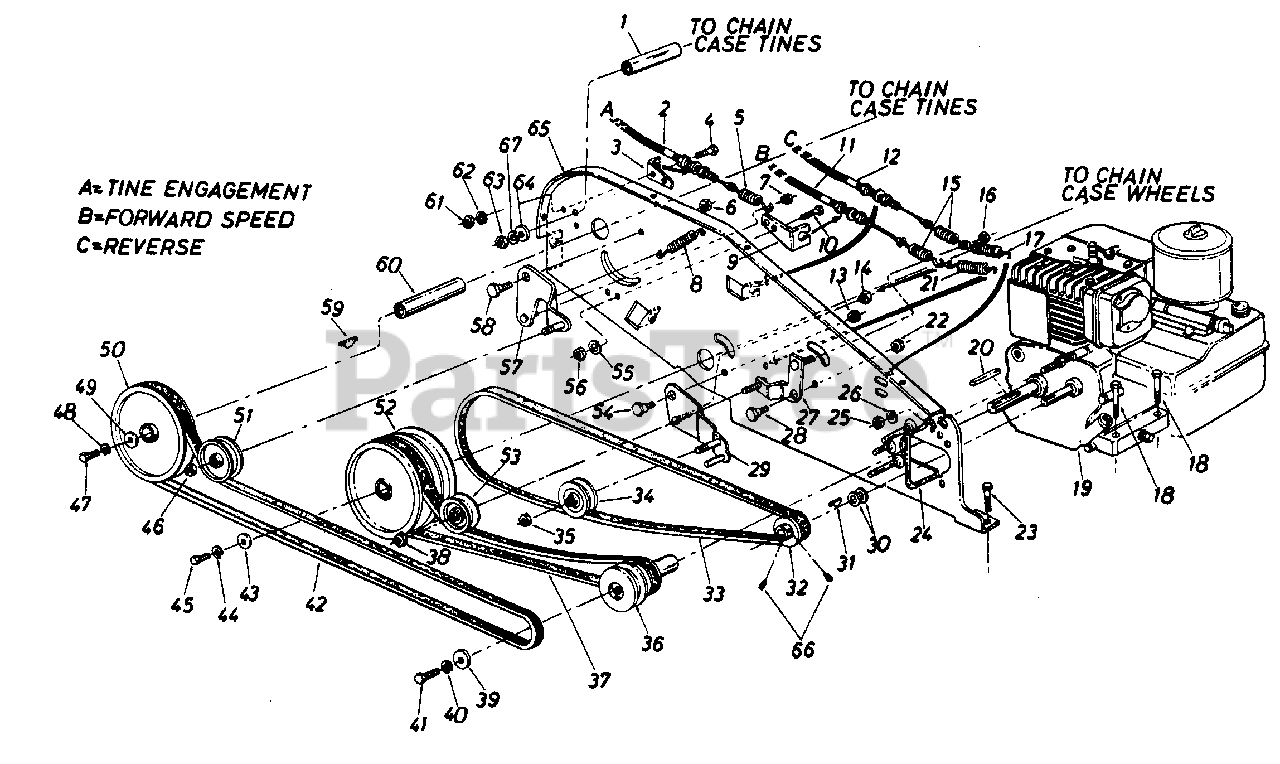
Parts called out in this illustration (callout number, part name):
1	Spacer.375" I.D. x .500" O.D. x 2.00" Lg.
2	Clutch Control Cable
3	Clutch Cable Bracket
4	Hex Bolt 5/16-18 x .75" Lg.*
5	Extension Spring .50" O.D. x 2.50" Lg.
6	Hex Cent. L-Nut 3/8-16 Thd.
7	Hex Cent. L-Nut 1/4" Thd.
8	Extension Spring .50" O.D. x 1.55" Lg.
9	Clutch Cable Bracket
10	Hex Bolt 5/16-18 x .75" Lg.*
11	Clutch Control Cable 42" Lg.
12	Clutch Control Cable 41" Lg.
13	Hex Cent. Nut 3/8-16 Thd.
14	Hex Cent. L-Nut 1/4-20 Thd.
15	Springs
16	Hex Cent. L-Nut 1/4-20 Thd.
17	Extension Spring .41" O.D. x 2.05" Lg.
18	Hex Bolt 5/16-18 x 1.50" Lg.*
20	Sq. Key 3/16 x 1.00" Lg.
21	Extension Spring .50" O.D. x 2.75" Lg.
22	Hex Cent. L-Nut 3/8-16 Thd.
23	Hex Bolt 5/16-18 x .75" Lg.*
24	Belt Keeper
25	Hex Nut 1/4-20 Thd.*
26	Bell-Wash. .265" I.D. x .75" O.D.
31	#5 Hi-Pro-Key 1/8" x 5/8" Dia.
32	1/2" V-Pulley 2.25" O.D. x .503" I.D.
33	"V"-Belt 1/2" X 43.0" Lg.
34	"V"-Belt Idler 2.62" O.D.
35	Hex Ins. L-Nut 3/8-24 Thd.
36	1/2" "V" Pulley Ass'y.
37	"V"-Belt 1/2" X 39.0" Lg.
38	Hex Ins. L-Nut 3/8-24 Thd.
39	Fl-Wash. .344" I.D. x 1.125" O.D.
40	L-Wash. 5/16" I.D.*
41	Hex Bolt 5/16-24 x 1.00" Lg.*
42	"V"-Belt 1/2" X 54.0" Lg.
43	Fl-Wash. 1/4" I.D. x .93" O.D.
44	L-Wash. 1/4" I.D.*
45	Hex Bolt 1/4-28 X .75" Lg.
46	Hex Ins. L-Nut 3/8-24 Thd.
47	Hex Bolt 1/4-28 X .75" Lg.
48	L-Wash. 1/4" I.D.*
49	Fl-Wash. 1/4" I.D. x .93" O.D.
50	Fl-Pulley w/ Flanges 6.0" O.D.
51	Fl-Idler w/ Flanges 3.75" O.D.
52	Double Fl-Pulley 5/8" I.D. x 6.0" O.D.
53	Fl-Idler with Flanges 2.12" O.D.
54	Shld. Bolt .500" Dia. x .170"Lg.
55	L-Wash. 5/16" I.D.*
56	Hex Nut 5/16-18 Thd.*
59	61 Hi-Pro-Key 3/16" x 5/8" Dia.
60	Spacer .647" I.D. x 2.75" Lg.
61	Hex Nut 5/16-18 Thd.*
62	L-Wash. 5/16" I.D.*
63	Hex Nut 5/16-18 Thd.*
64	Fl-Wash. .406" I.D. x .750" O.D.
65	Side Plate Ass'y.
66	Set Scr. 1/4-28 X .25" Lg.
67	L-Wash. 5/16" I.D.*
